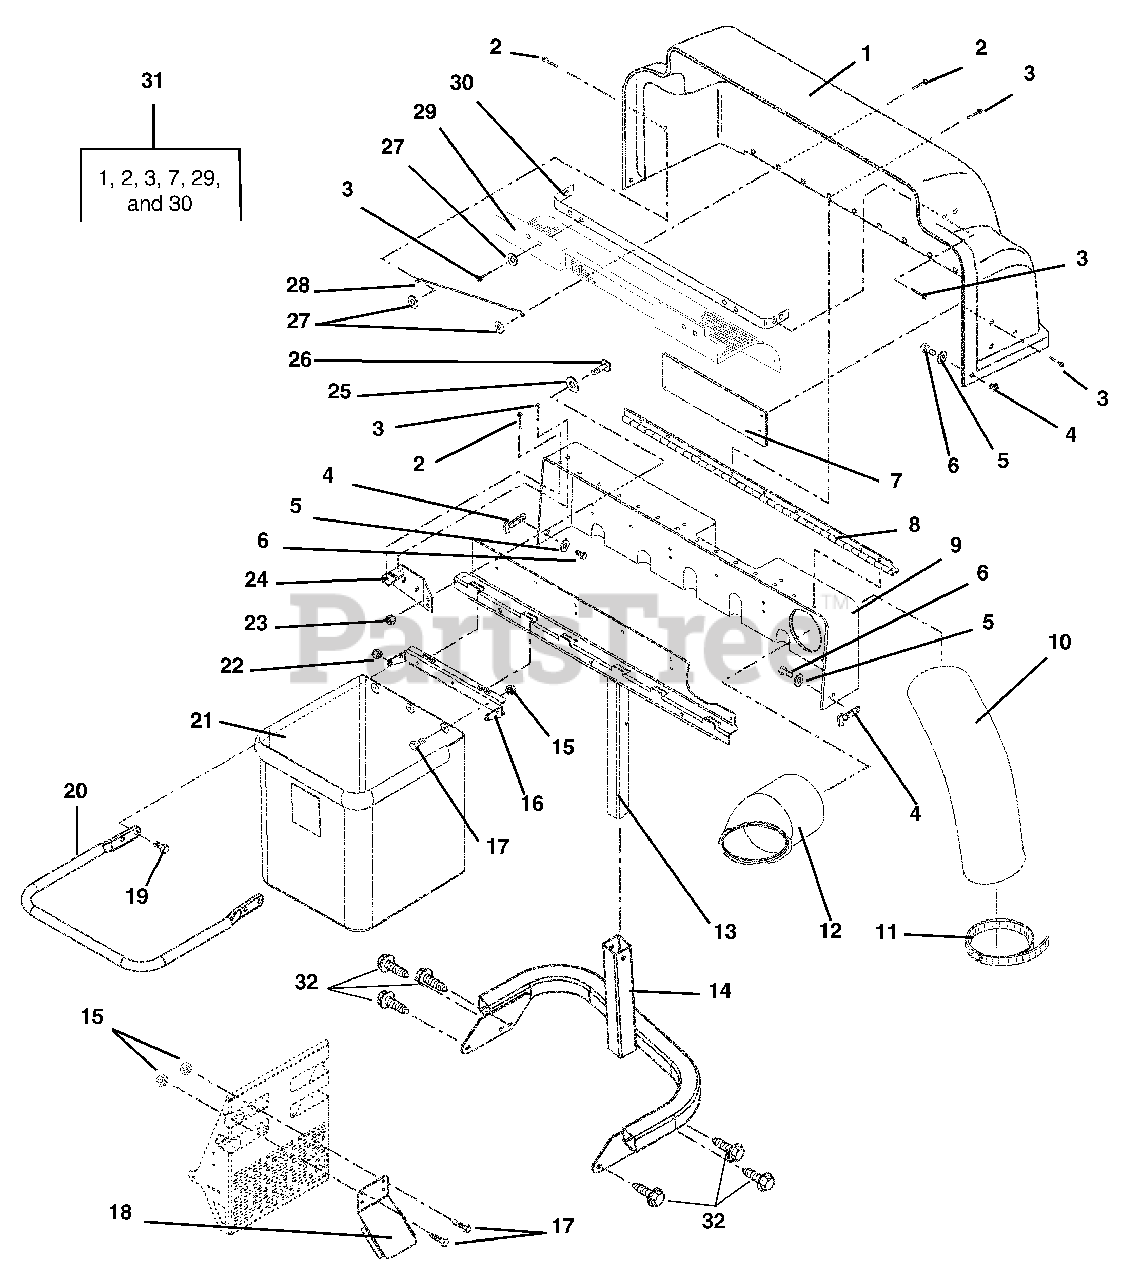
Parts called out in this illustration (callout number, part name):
1	HINGED COVER
2	RVT-POP.187X.527 DOME ST
3	RVT-POP .187X.402 DOME ST
4	LATCH, RUBBER
5	@WSHR-FL-STL.219X.50X.049 YWZC
6	@SCR-MCH 10-24X.50 HWH YWZC
8	HINGE- 2.0"X35.0"
9	STATIONARY COVER
10	HOSE 7 X 45
11	CLAMP-HOSE WRM 2.13/8.62X.56
12	BAGGER BOOT - UPPER
13	WELDMENT-BAGGER FRAME
14	WMT, BAGGER MNT (IZ)
15	@NUT-LK-CTR .25-20 YWZC
16	WMT, HANGER FRAME
17	@BLT-HEX .25-20X.50 GR5 YWZC
18	DEFLECTOR, EXHAUST
19	@BLT-RHDSSQNK .31-18X.75 G5YZ
20	FRAME-BAG SUPPORT
21	BAG-MESH ASSIST BAGGER
22	@NUT-SPNLK-FLG .312-18 YWZC
23	@NUT-LK-CTR .31-18 YWZC
25	@WSHR-FL-STL.38X.875X.083 YWZC
26	@BLT-HEX .31-18X.75 GR5 YWZC
27	@WSHR-FL-STL .188X.438X.049 YZ
30	SCREEN MOUNTING BRACKET
31	HINGED COVER W/DECAL
32	@SCR-TAP .38-16X.75 HWH TR YWZ
